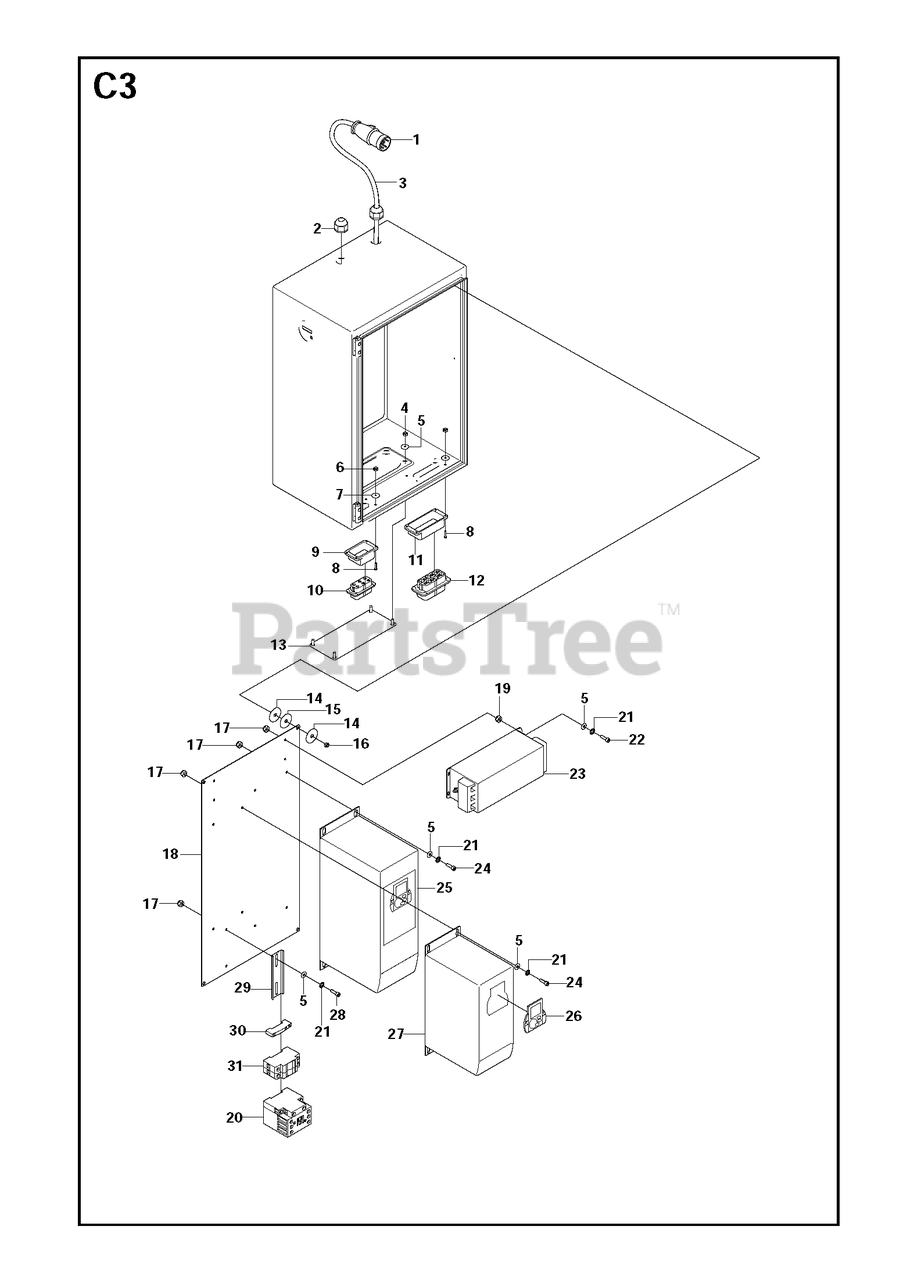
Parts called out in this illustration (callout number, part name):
4	HEXAGON LOCKING NUT
6	HEXAGON LOCKING NUT
16	HEXAGON LOCKING NUT
